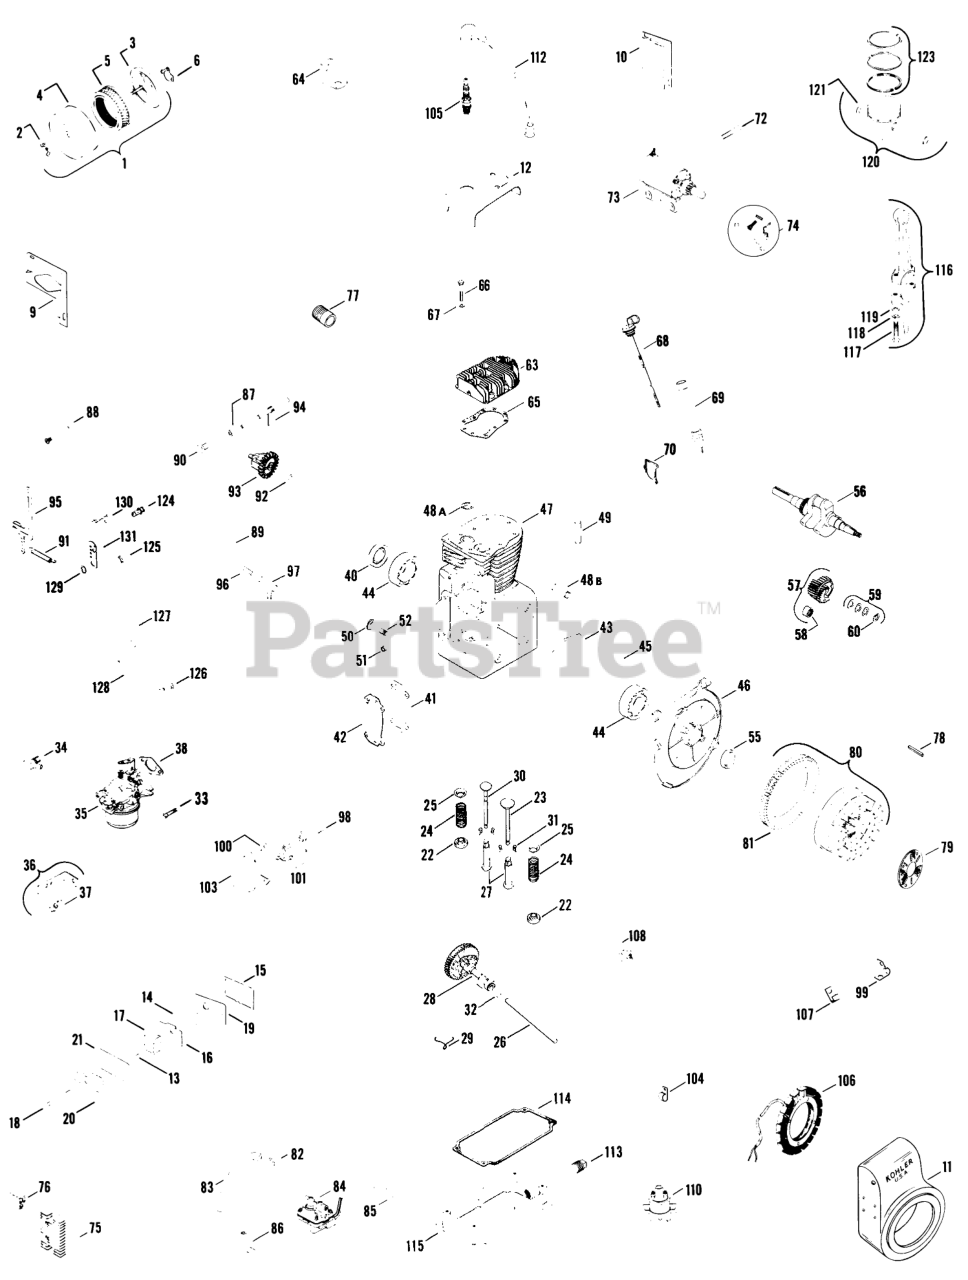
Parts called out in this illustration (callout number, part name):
1	Cleaner-Air Assembly
2	Nut-Wing
3	Base-Air Cleaner
4	Cover-Air Cleaner
5	Element
6	Gasket-Air Horn
9	BaffLe side air
10	Baffle cylinder
11	Housing-Blower
12	Baffle-Head
13	Seal
14	Reed
15	Gasket
16	Baffle breather
17	Filter Breather
18	Stud, valve cover
19	Plate
20	Cover valve
21	Gasket
22	Retainer-Spring
23	Valve-Intake
24	Spring
25	Retainer-Spring
26	Pin (Service)
27	Tappet
28	Camshaft-assembly
29	Spring-Actuating
30	Valve, exhaust
31	Keeper, Valve
32	Spacer
33	Screw sitd. hd.
34	Elbow
35	Carburetor-assembly
35	Repairkit
36	Bracket, choke
37	Clip
38	Gasket
40	Seal rear oil
41	Gasket
42	Cover
43	Gasket
44	Ball Bearing
45	Gasket
46	Plate Bearing
47	Block, cylinder-assembly (Use B-237416 Miniblock)
48A	Insert
48B	Shaft
49	Guide Valve
50	Plug
51	Bearing
52	Shaft-Govemor
55	Seal, Front OiI
56	Crankshaft
57	Gear
58	Bearing,needle
59	Kit, spacer
60	Retainer
63	Belt Guide
64	Lift Cable
65	Gasket-Head
66	Screw
66	Screw-H.C.
67	Washer
68	Dipstick
69	Tube, fill
70	Gasket
72	Screw
73	Starter
74	Kit, Brush & Spring
75	Regulator
76	Connector
77	Washer
77	Nut
78	Key
79	Screen grass
80	Flywheel-Assembly
81	Gear Ring
82	Clamp
83	Line Fuel
84	Pump, fuel
85	Gasket, pump
86	Elbow
87	Spacer
88	Pin-GovemorStop
89	Retainer Rod
90	Bushing
91	Spring-Governor
92	Washer
93	Gear, Governor
94	Shaft, Governor
95	Lever, Governor
96	Rod ball joint
97	Ball Joint
98	Rod, breaker
99	Clip
100	Gasket, Cover
101	Breaker
103	Cover breaker
104	Clip
105	Plug, spark
106	Stator
107	Clip
108	Condenser
110	Coil
112	Kit, Hi-Tension
113	Plug
114	Gasket
115	Base, oil pan
116	Rod, Connecting
116	Rod-Conn. Assy. (.010)
117	Screw, connecting rod
118	Washer
119	Washer
120	Piston-assembly (Std.) (Includes pin & retainers)
120	Piston-assembly (.303)(Includes pin & retainers)
120	Piston-assembly (.010)(Includes pin & retainers)
120	Piston-assembly (.020)(Includes pin & retainers)
120	Piston-assembly (.030)(Includes pin & retainers)
121	Pin, Retainer
123	Ring set-Std. & .003 (Svc.)
123	Ring set-.010 (Service)
123	Ring set-.020 (Service)
123	Ring set-.030 (Service)
124	Clamp, swivel wire
125	Spacer
126	Retainer Rod
127	Bellcrank
128	Rod, throttle
129	Washer
130	Spacer
131	Bracket
131	Gasket Set
131	Miniblock
131	Short Block
131	Service Engine
